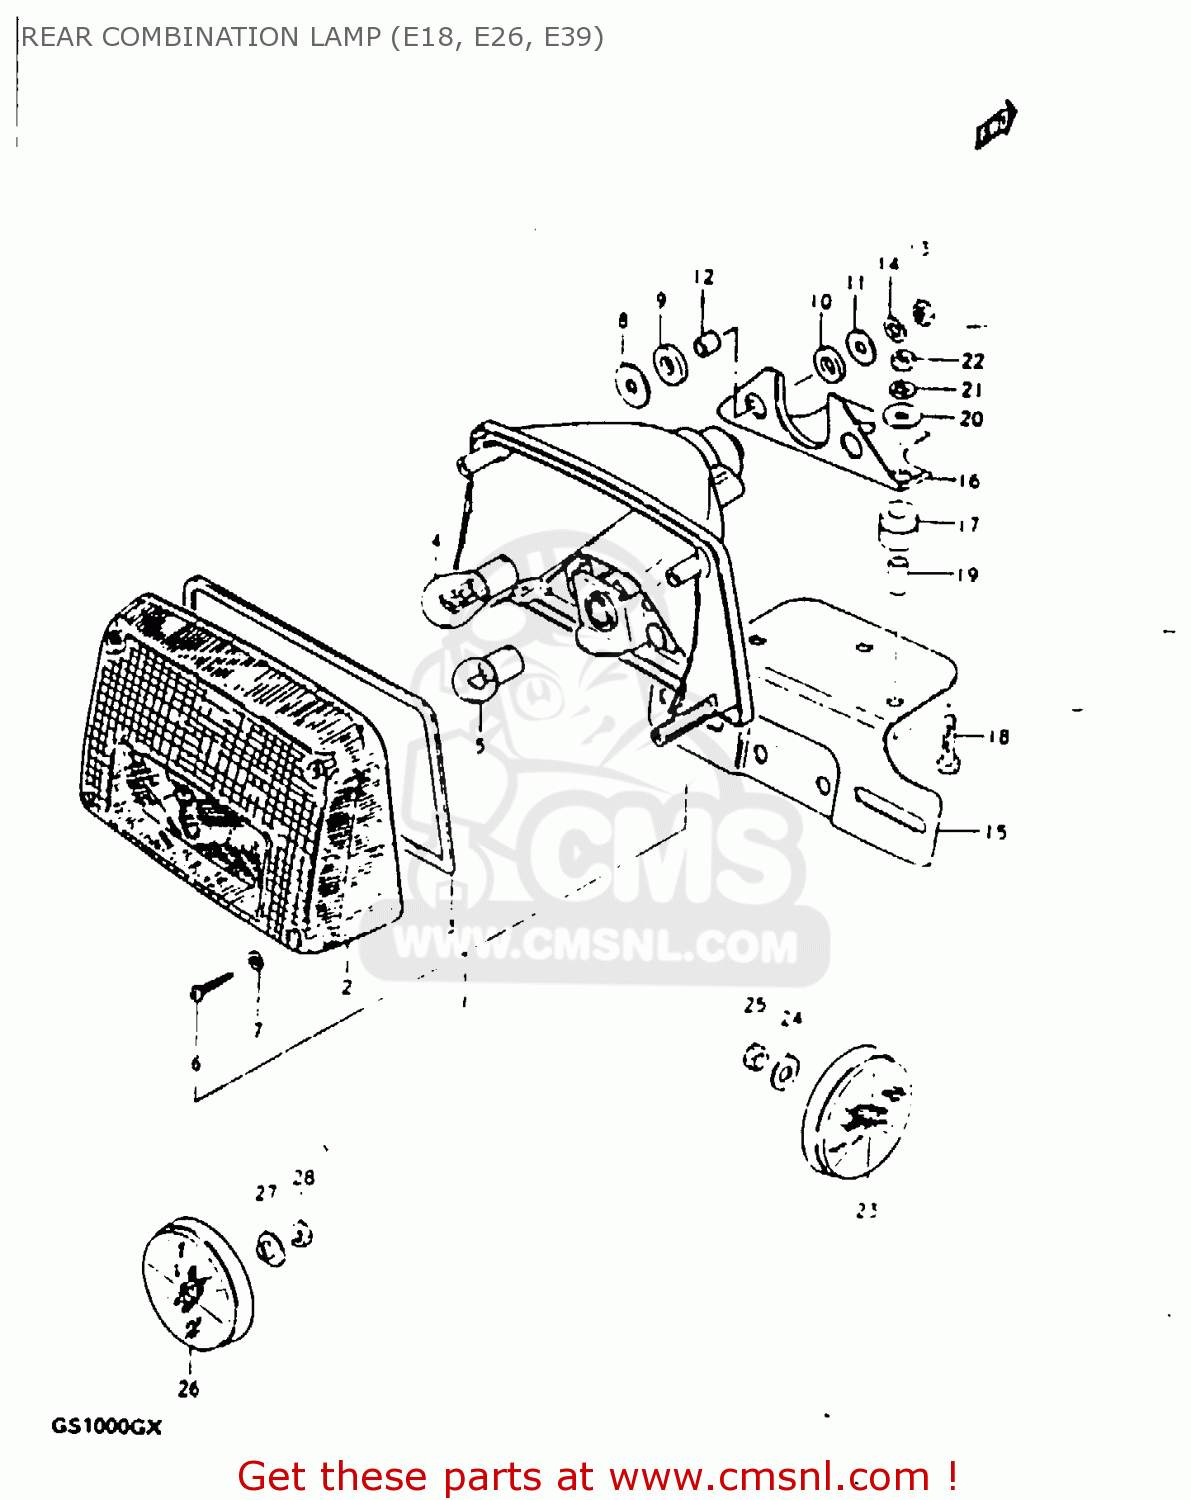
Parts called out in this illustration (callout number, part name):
1	LAMP, REAR COMBINATION
2	LENS
3	GASKET (NAS)
4	BULB 12V21/5W
5	BULB
6	BOLT
7	GASKET (NAS)
8	WASHER
9	CUSHION
10	CUSHION
11	WASHER(6,5X22X1.6)
12	SPACER(6.1X9X7.5)
13	NUT
14	LOCK WASHER
15	BRACKET, LICENCE PLATE
16	BRACKET,LICENSE PLATE
17	CUSHION, BRACKET
18	BOLT
19	SPACER (6.4X9X15.5)
20	WASHER
21	LOCK WASHER
22	NUT
23	REFLEX REFLECTOR,RR
24	WASHER
25	NUT
26	REFLEX REFLECTOR,RR
27	SPACER
28	NUT
